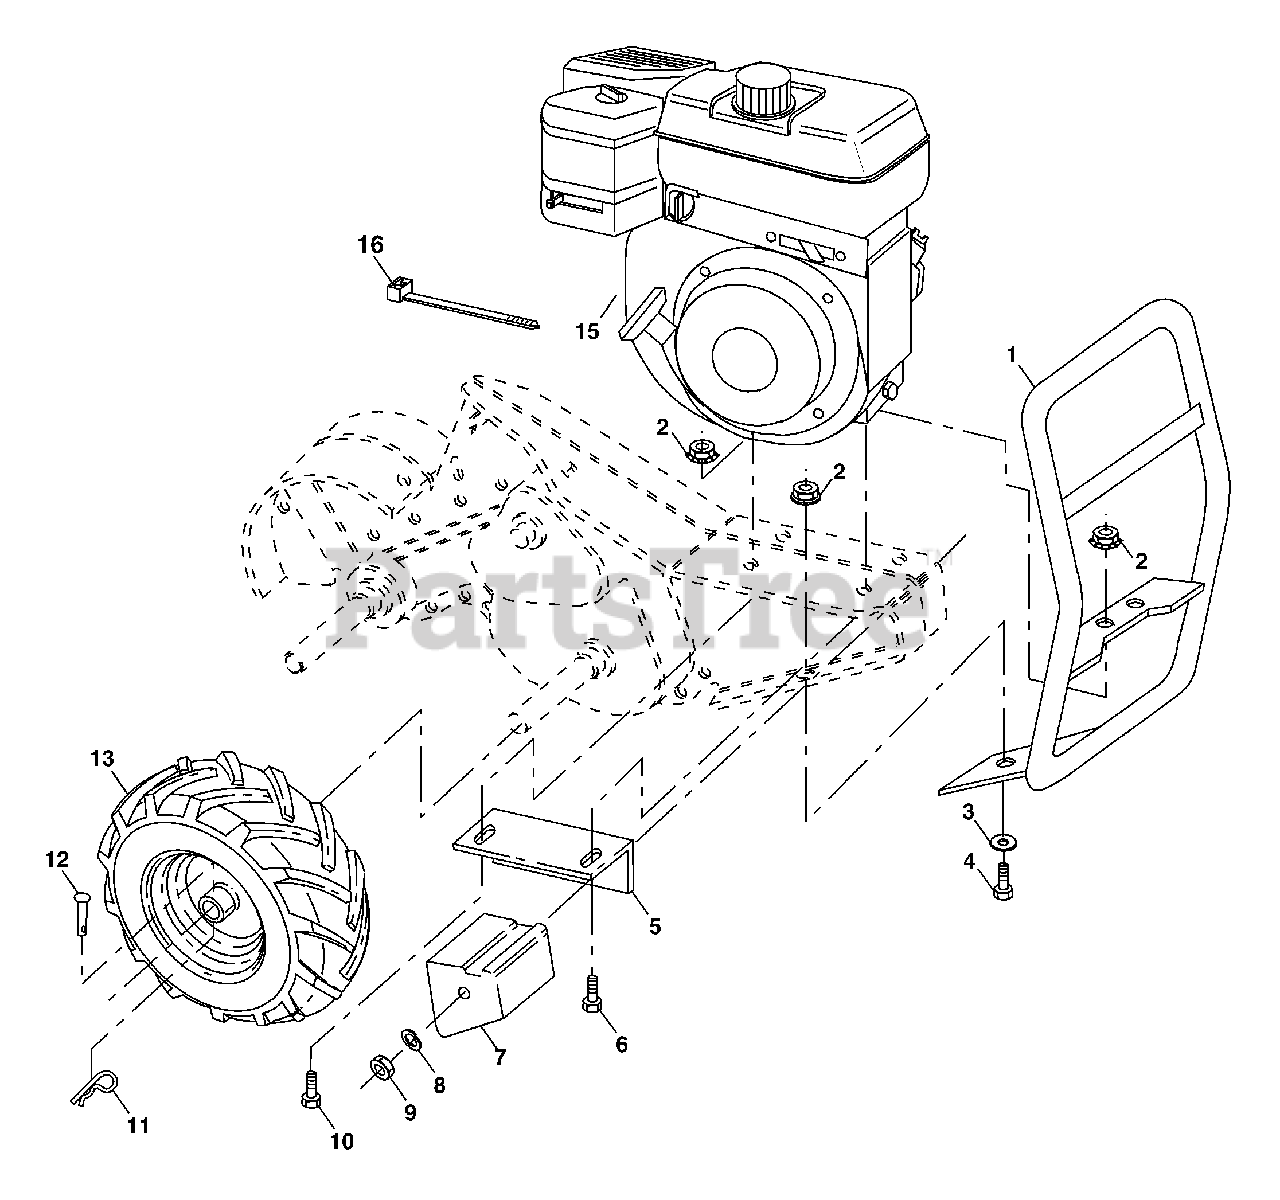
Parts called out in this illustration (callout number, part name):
2	Locknut, Hex, Flange 5/16-18
3	Washer 11/32 x 11/16 x 16 Ga.
4	Bolt, Hex 5/16-18 x 3/4
5	Bracket, Reinforcement
6	Bolt, Hex 5/16-18 x 1-3/4
7	Counter Weight, R.H.
8	Washer, Lock 3/8
9	Nut, Hex 3/8-16
10	Bolt, Hex 5/16-18 x 1-1/2
11	Clip, Hairpin
12	Rivet, Drilled
13	Tire
13	Rim
13	Tire Valve
16	Tie Cable
